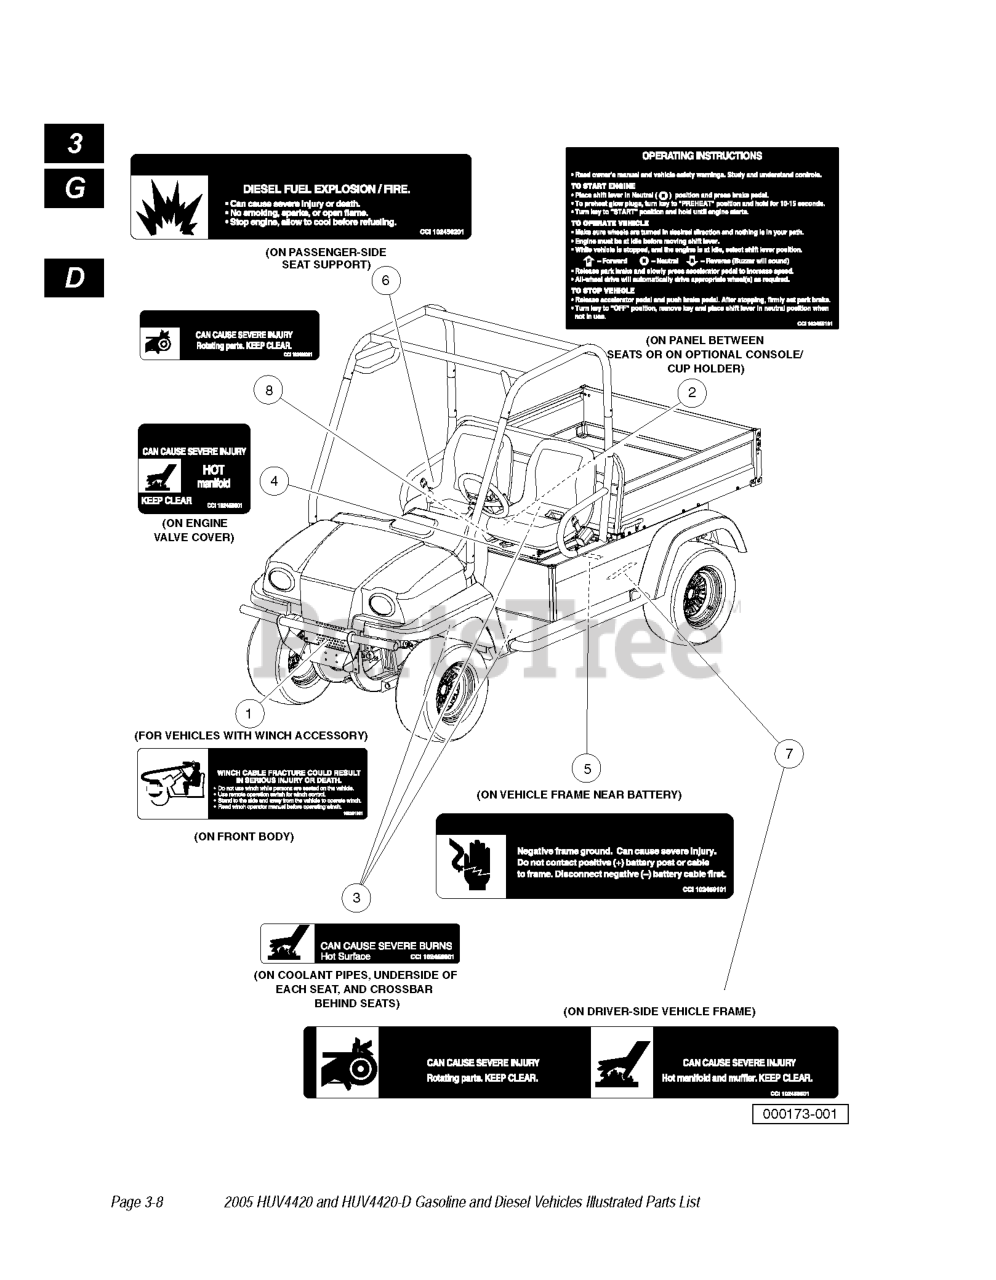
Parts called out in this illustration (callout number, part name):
1	DECAL-WINCH KIT
2	DECAL, OPER INSTR AWD DIESEL
3	DECAL, WARNING HOT SURFACE
4	DECAL, WARNING HOT MANIFOLD
5	DECAL, WARNING GROUND
6	DECAL, WARNING DIESEL FUEL
7	DECAL, WARNING ROTATE/HOT
8	DECAL, WARNING ROTATING PARTS
